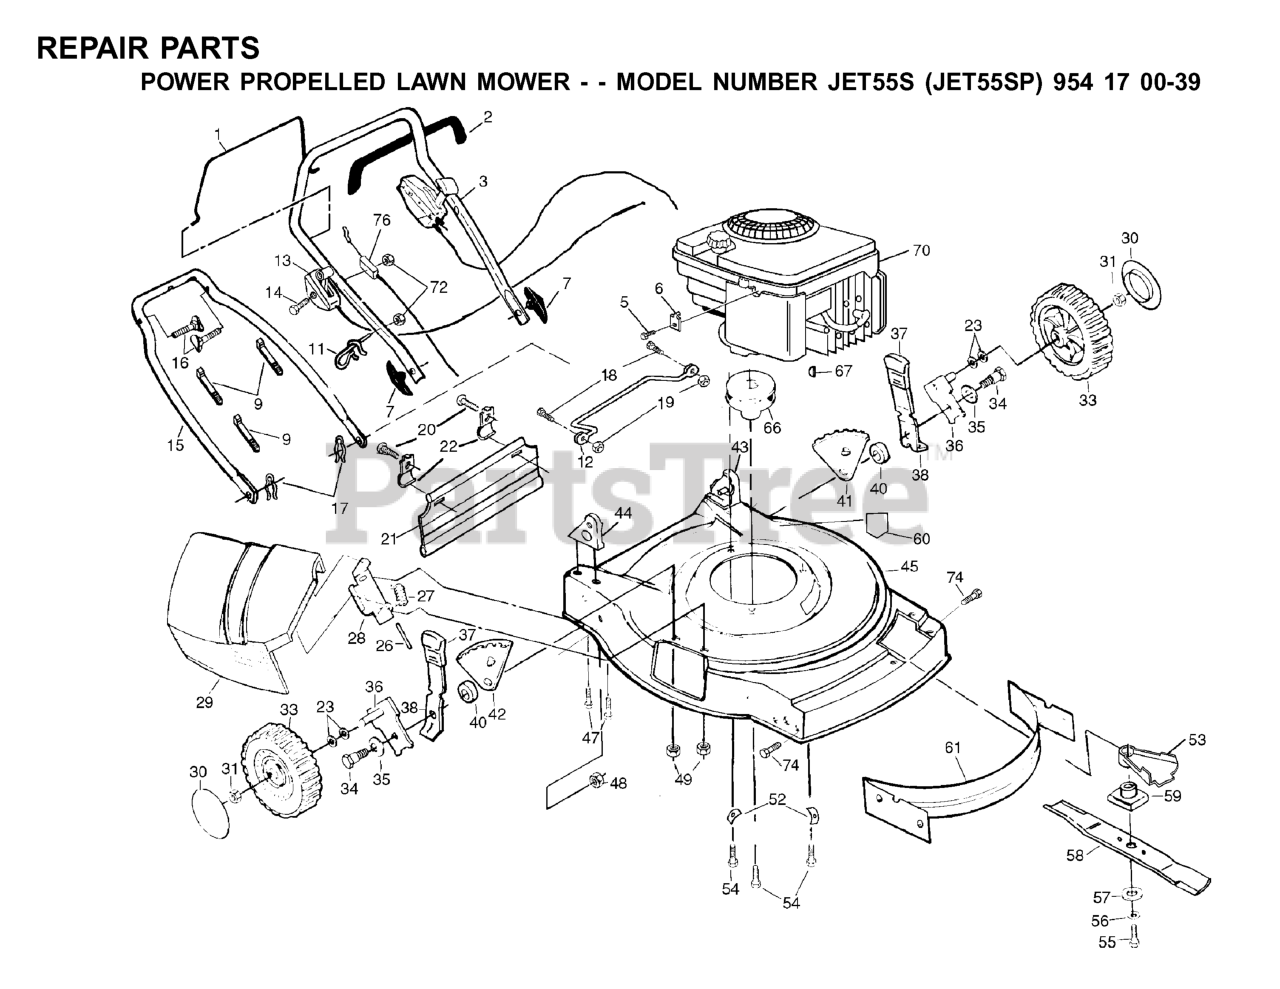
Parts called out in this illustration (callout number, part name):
1	BAIL.CNTRL.DLX.CK
2	GRIP.HANDLE.FOAM
3	HANDLE.UP.DLX.COMF.W/GRIP.GREY
5	SCREW.HEX.HEAD.WASHER.10-16
6	WASHER
7	HANDLE KNOB
9	TIE GUIDE
13	THROTTLE CONTROL
14	SCREW 1/4-20 X 2.12
15	LOWER HANDLE
16	HANDLE BOLT
17	HAIRPIN COTTER
18	REPL BY 817 02 10-08
20	TAPPING SCREW
21	REAR SKIRT
22	BRACKET DEFL PM
23	WAVE WASHER
26	ROD.HINGE.COMBI-C
28	BRACKET PM
29	DISCHARGE GUARD
30	HUBCAP.8".GREY
31	HEX FLANGE LOCKNT
33	WHEEL.8X2.PR.LP.RAD.GREY
34	BOLT
35	WASHER.BELLEVILLE (3 2 LB)
36	AXLE ARM
37	SELECTOR KNOB
40	RP SPACER HT ADJ
41	WHL ADJ BRKT RF/LR
42	WHL ADJ BRKT LF/RR
43	HANDLE BRACKET ASM. LH
44	HANDLE BRACKET ASM. RH
47	SCREW.5/16-18X3/4
48	LOCKNUT PM
49	NUT
52	WASHER.ENGINE.BZP
53	DEBRIS SHIELD
54	BOLT 3/8-16X1-1/8
55	SCREW, HEX HD 3/8-24 X 1-3/8
56	LOCKWASHER
57	WASHER,HARDEN
58	22" Blade
59	BLADE ADAPTOR
60	DECAL MOWER CUT/FINGER
66	ENGINE.PULLEY.FWG
67	HI PRO KEY PM WSL
72	NUT
74	SCREW 1/4X20
76	ENGINE ZONE CONTROL CABLE
